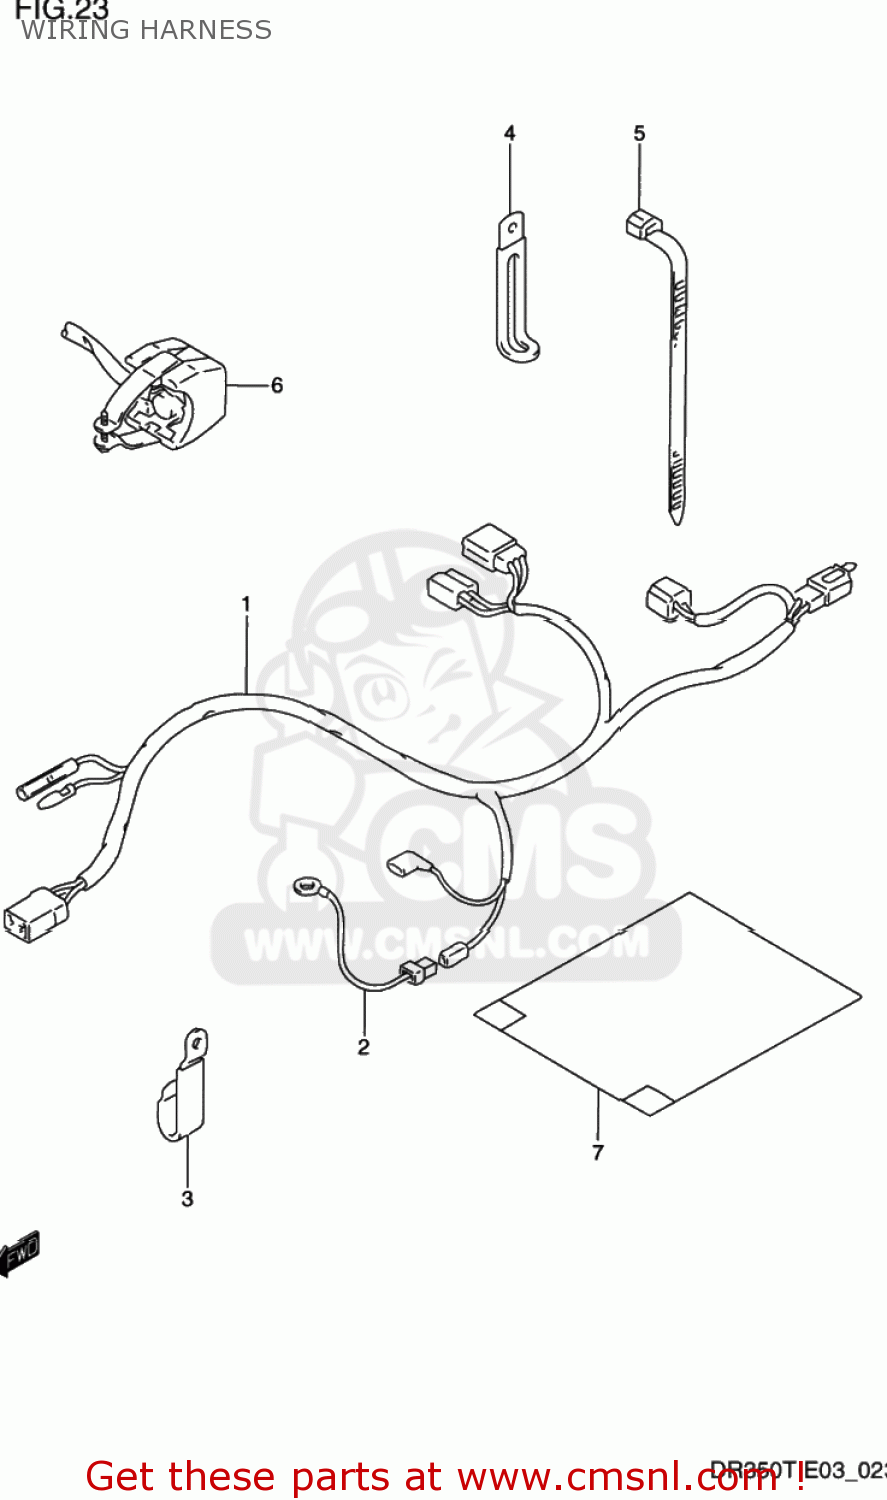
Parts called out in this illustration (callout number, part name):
1	HARNESS,WIRING
2	WIRE
3	CLAMP
4	CLAMP(L:45)
5	CLAMP(L:95)
6	SWITCH ASSEMBLY
7	COVER,WIRING HARNESS
